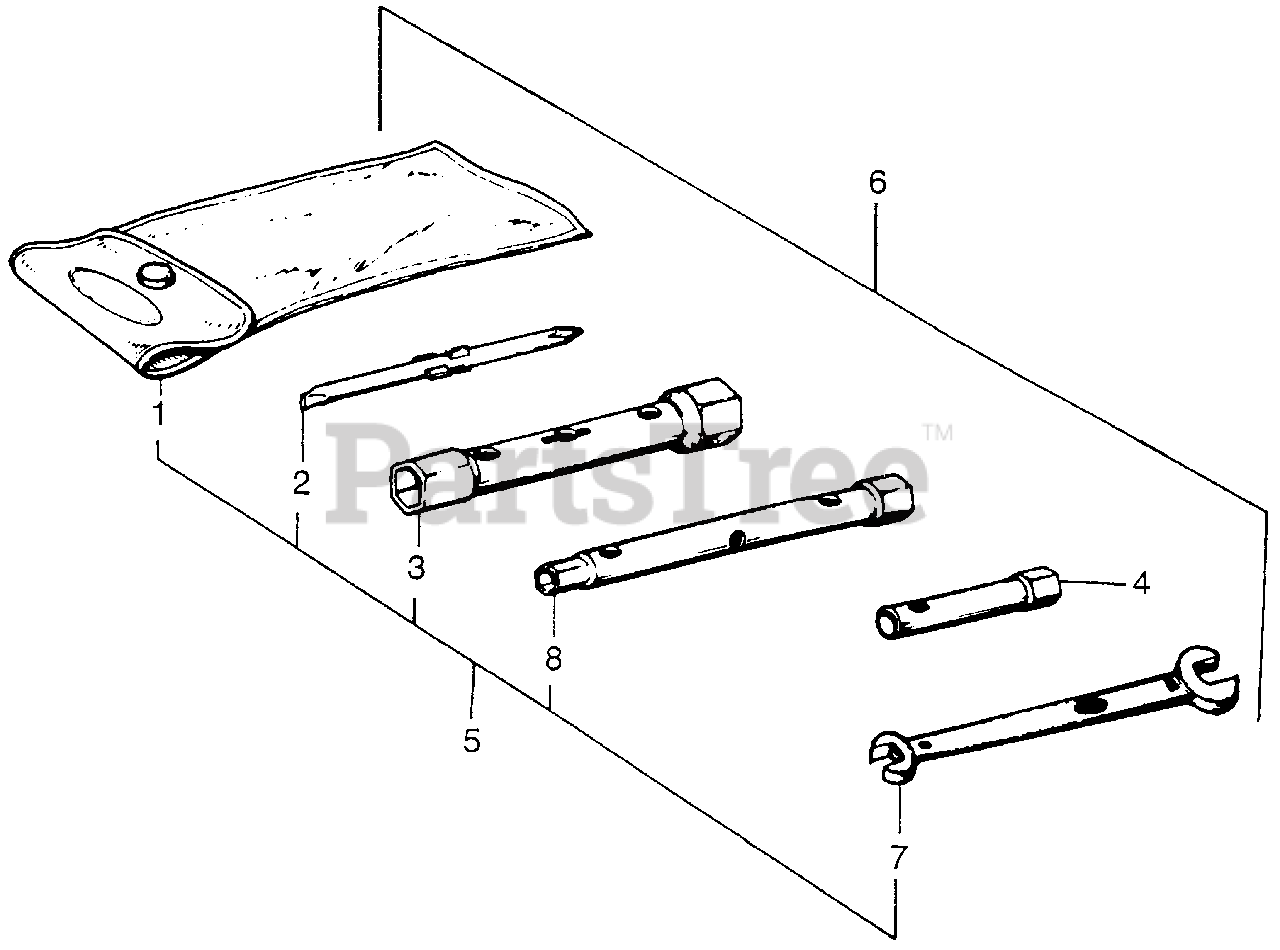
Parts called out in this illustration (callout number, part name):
3	WRENCH, SPARK PLUG (NOT AVAILABLE)
4	WRENCH, BOX (12MM) (NOT AVAILABLE)
5	TOOL ASSY. (NOT AVAILABLE)
6	TOOL ASSY.
7	WRENCH (10X12) (OPEN END)
8	WRENCH (10X14) (OPEN END)
